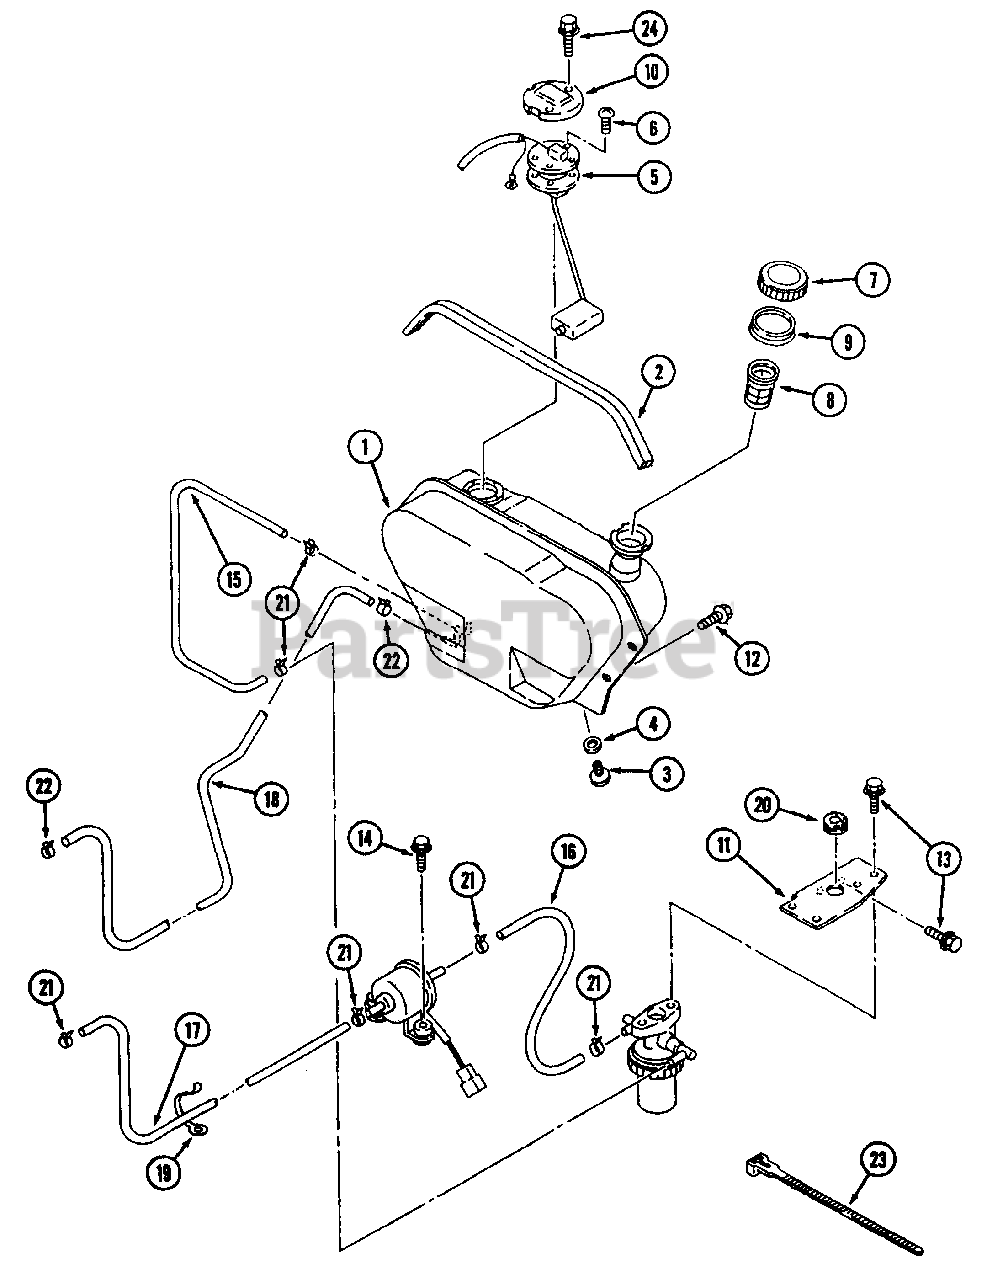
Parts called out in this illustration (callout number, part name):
10	Cover, Fuel Unit
11	Bracket, Filter
14	Bolt
17	Hose
18	Hose
